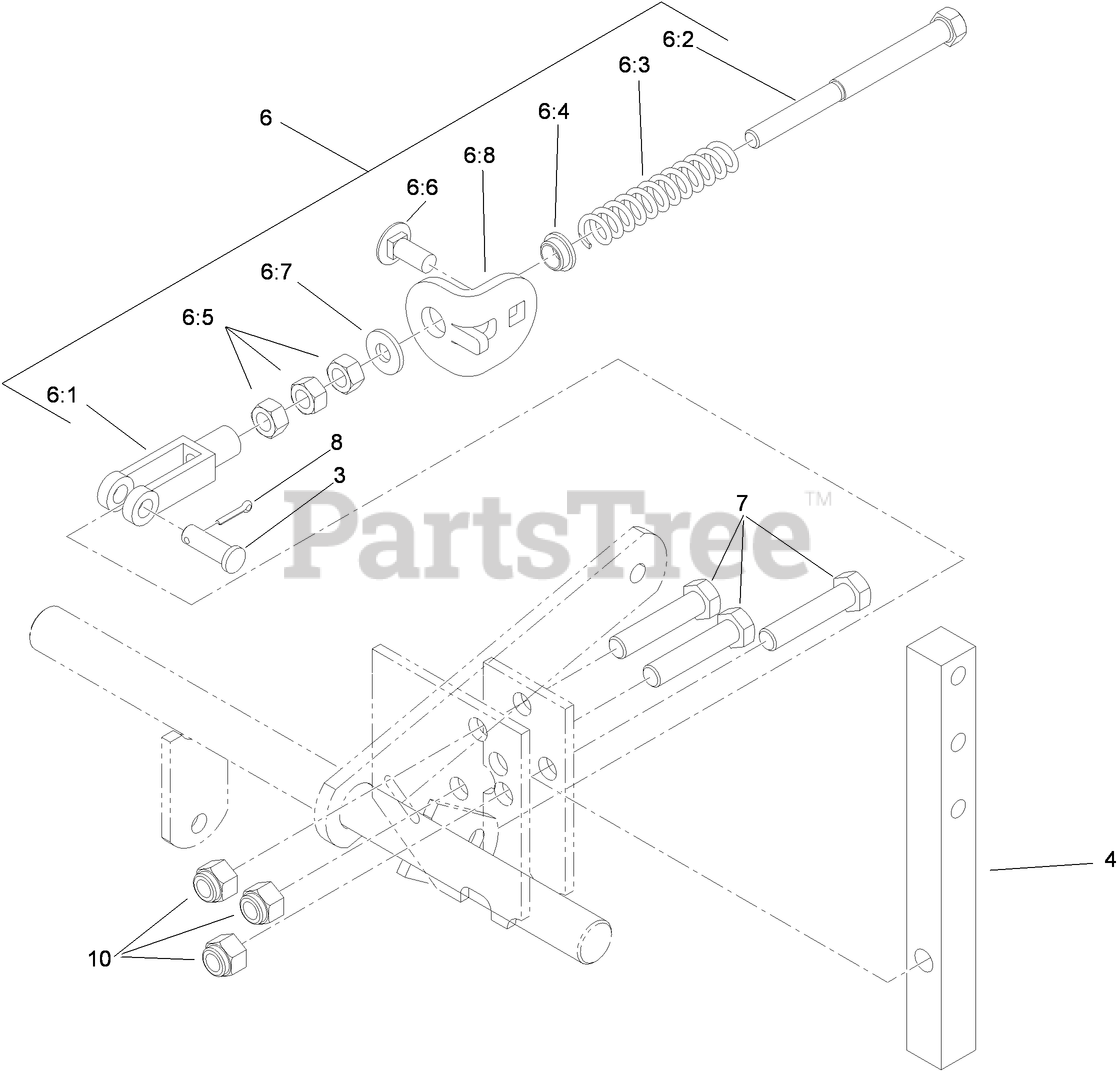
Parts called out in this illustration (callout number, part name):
3	PIN-CLEVIS
4	ARM-SHAFT, CONTROL
6	NEUTRAL RETURN ASM
6:1	YOKE-ADJUSTABLE
6:2	BOLT-RETURN, NEUTRAL
6:3	SPRING-RETURN, NEUTRAL
6:4	BUSHING-NYLON, FLANGED
6:5	NUT-HEX
6:6	SCREW-CARR
6:7	WASHER-FLAT
6:8	TAB-ADJUSTMENT
7	SCREW-HH
8	PIN-COTTER
10	NUT-LOCK, NI
